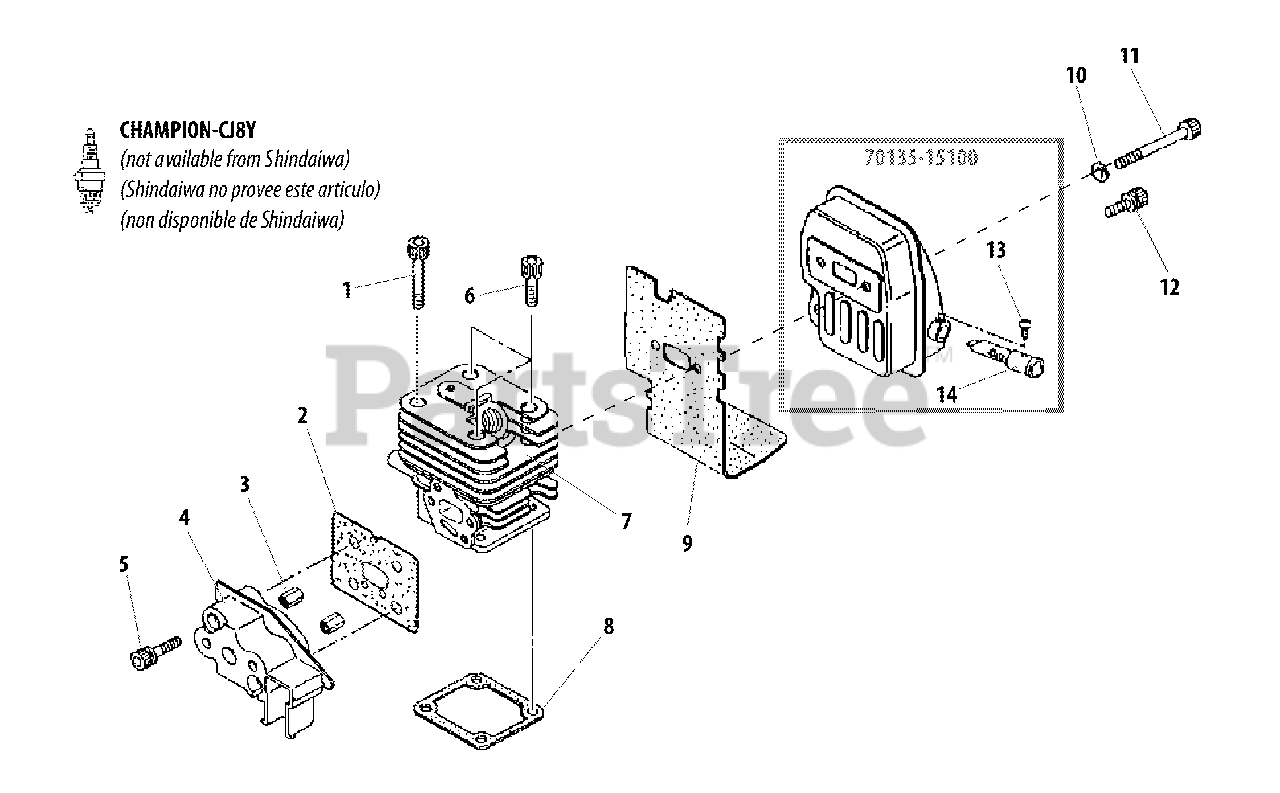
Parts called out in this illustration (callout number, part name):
1	SCREW - 5X35
2	GASKET
3	NUT
4	INSULATOR
5	SCREW - 5X30
6	SCREW - 5X16
7	CYLINDER
8	GASKET, CYLINDER
9	GASKET, EXHAUST
10	WASHER - 5
11	SCREW - 5X50
12	SCREW - 5X12
13	SCREW - 3X6
14	SCREEN, SPARK ARRESTOR
A	MUFFLER ASSY
